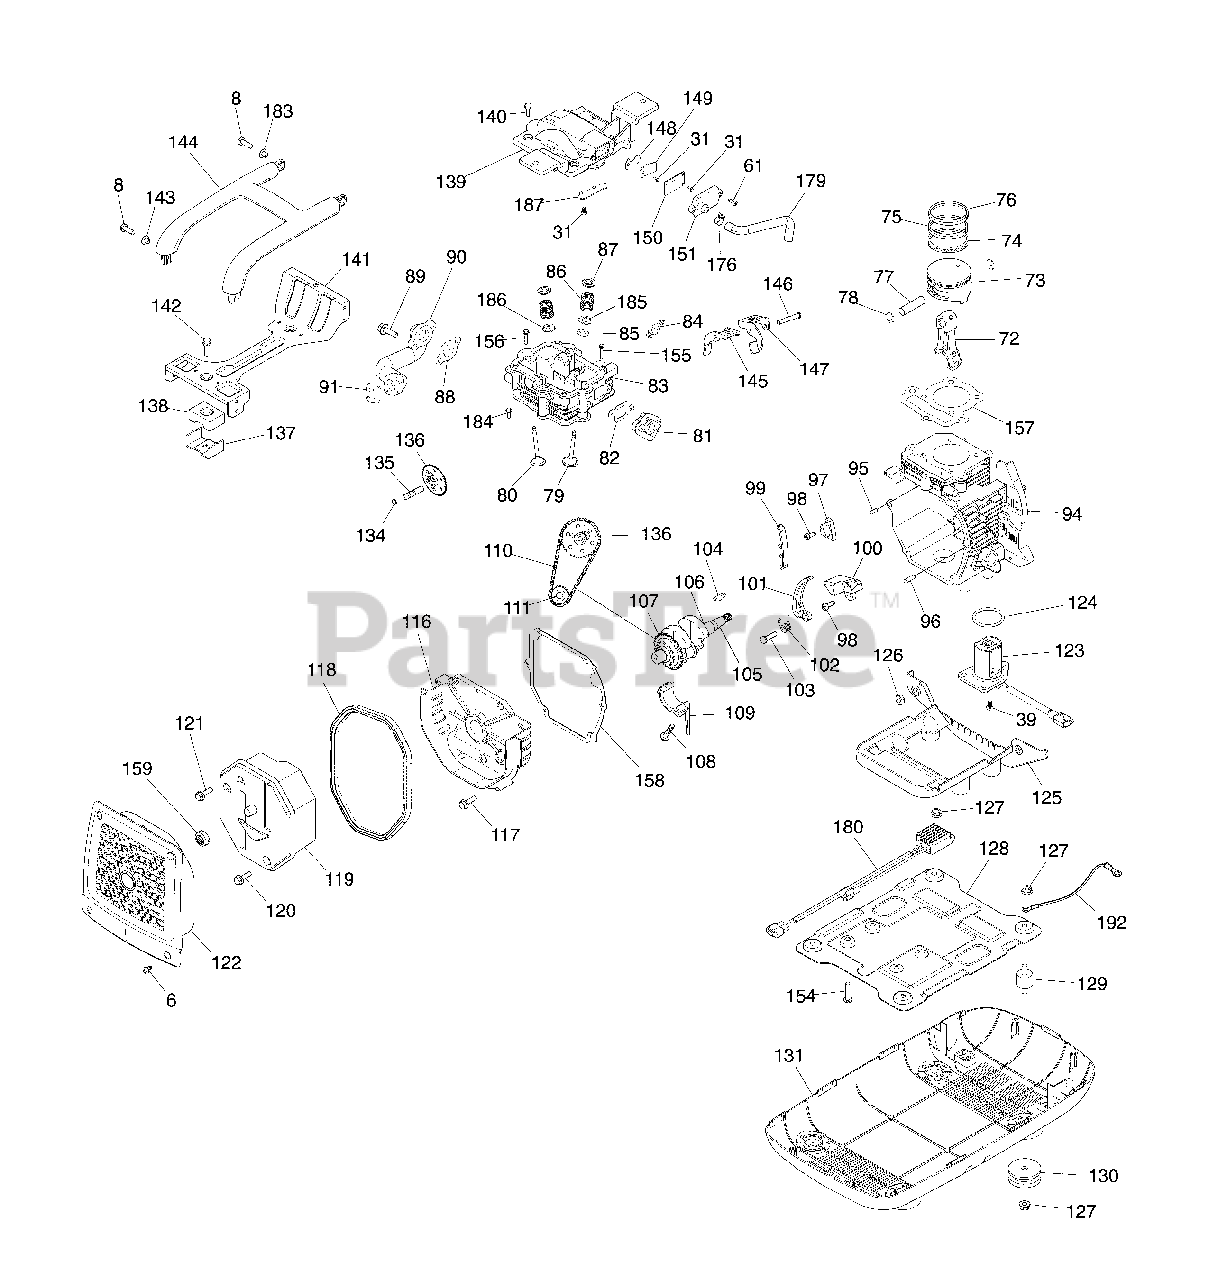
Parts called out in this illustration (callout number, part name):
31	BOLT
61	SCREW
72	ROD
73	PISTON
74	RING
75	RING
76	RING
77	PIN
78	RETAINER-PIN
79	VALVE-INTAKE
80	VALVE-EXHAUST
83	CYLINDER HEAD
85	SEAL-VALVE OIL
86	SPRING
87	SEAT-VALVE
89	BOLT
90	MANIFOLD-EXHAUST
94	CRANKCASE
95	PIN
96	PIN
97	BLOCK
98	SCREW
99	BRACKET
100	BRACKET
101	ARM-TENSION
102	SPRING
103	PIN
104	KEY
105	CRANKSHAFT
106	BEARING
107	GEAR
108	BOLT
109	COVER
110	CHAIN
111	WHEEL-CHAIN
116	COVER-CRANKCASE
117	BOLT
118	BLOCK-RUBBER
119	MUFFLER
120	BOLT
121	BOLT
122	GUARD-MUFFLER
124	O-RING, 33.5 x 2.65
125	COVER
126	NUT
129	MOUNT-VIBRATION
130	MOUNT-VIBRATION
134	O-RING
135	SHAFT
136	CAM-ASSEMBLY
137	BRACKET
138	MOUNT-VIBRATION
140	BOLT
141	BRACKET
142	BOLT
145	ARM-EXHAUST VALVE
146	PIN
147	ARM-INTAKE VALVE
150	BOARD-VALVE
151	BOARD-VALVE
154	BOLT
155	BOLT
156	BOLT
157	GASKET
158	GASKET-CRANKCASE
176	CLAMP
180	REGULATOR-VOLTAGE
184	BOLT
185	SEAT
186	SEAT
187	PLATE
